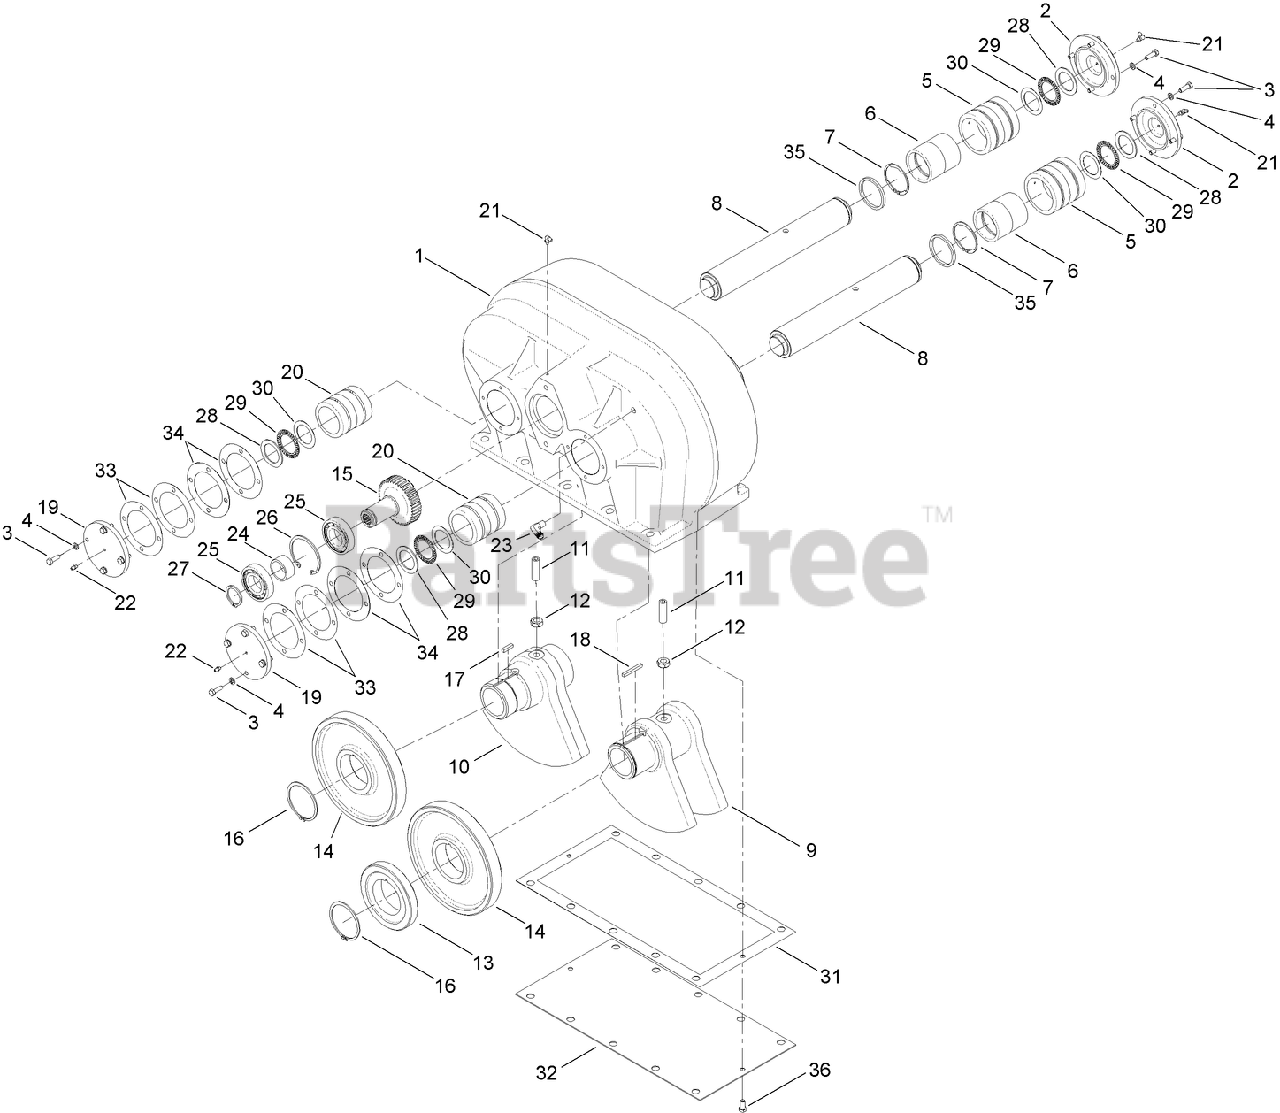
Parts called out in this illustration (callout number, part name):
1	CASE-GEAR
2	CAP-BEARING, LARGE
3	SCREW-HH
4	WASHER-LOCK
5	BEARING-ROLLER (MATCHED SET)
6	RACE-BEARING (MATCHED SET)
7	RING-RETAINING
9	WEIGHT-SHAKER
10	WEIGHT-SHAKER
11	SCREW-HSH
12	NUT-HEX, JAM
13	GEAR-DRIVEN
15	GEAR-DRIVE
16	RING-RETAINING
19	CAP-BEARING
20	BEARING-ROLLER (MATCHED SET)
21	FITTING-GREASE, 90 DEG
22	FITTING-GREASE
23	FITTING-ELBOW, 90 DEG
25	BEARING
26	RING-RETAINING, INTERNAL
27	RING-RETAINING, EXTERNAL
28	WASHER-THRUST
29	BEARING-THRUST, NEEDLE
30	WASHER-THRUST
32	PLATE-COVER, GEARBOX
33	GASKET-COVER
34	GASKET-COVER
36	SCREW-HH
